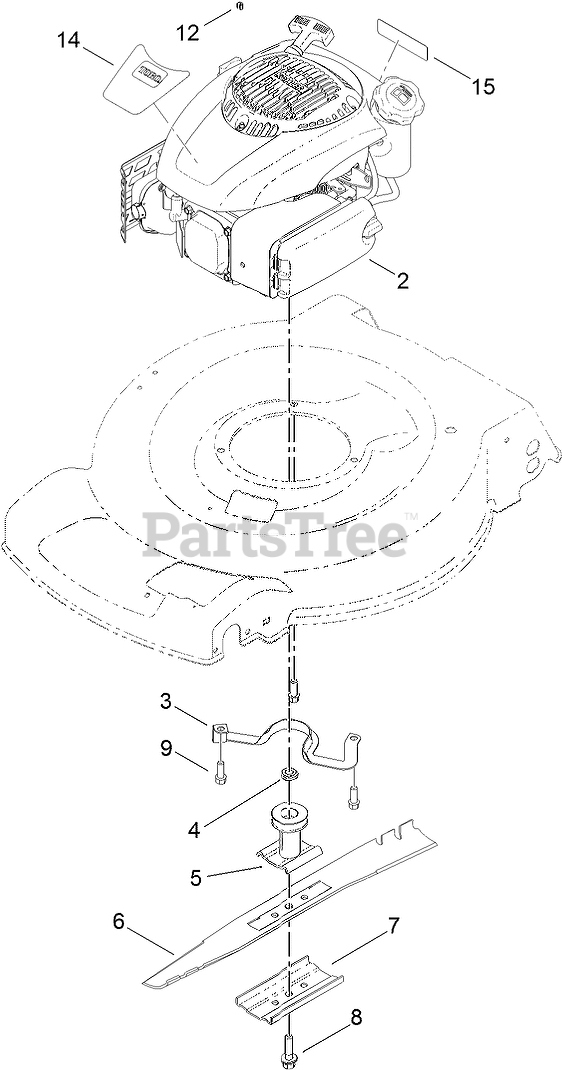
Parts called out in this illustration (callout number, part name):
3	Guide-Belt
4	Spacer-Driver
5	DRIVER-BLADE
6	BLADE-22 INCH
7	SUPPORT-BLADE
8	BOLT-BLADE
9	SCREW-TAPTITE
12	STOP-ROPE
14	DECAL-SHROUD
15	DECAL-ARRESTER, SPARK
